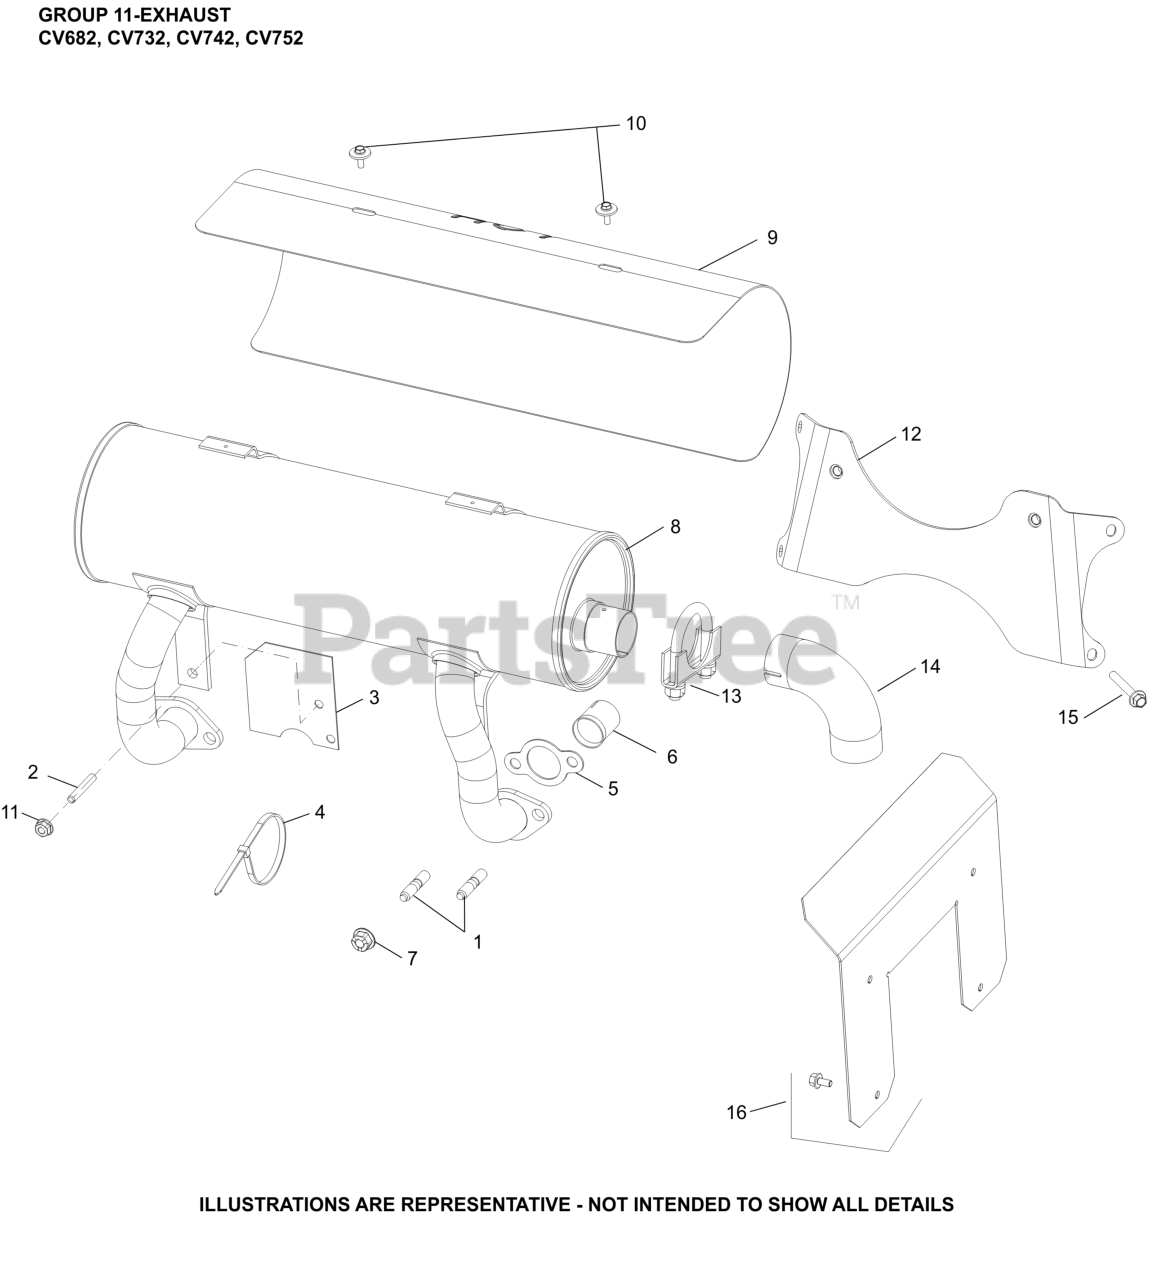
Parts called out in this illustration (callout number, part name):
1	STUD, METRIC EXHAUST
5	GASKET, EXHAUST-(#2504117S)
7	NUT, FLG M8X1.25
